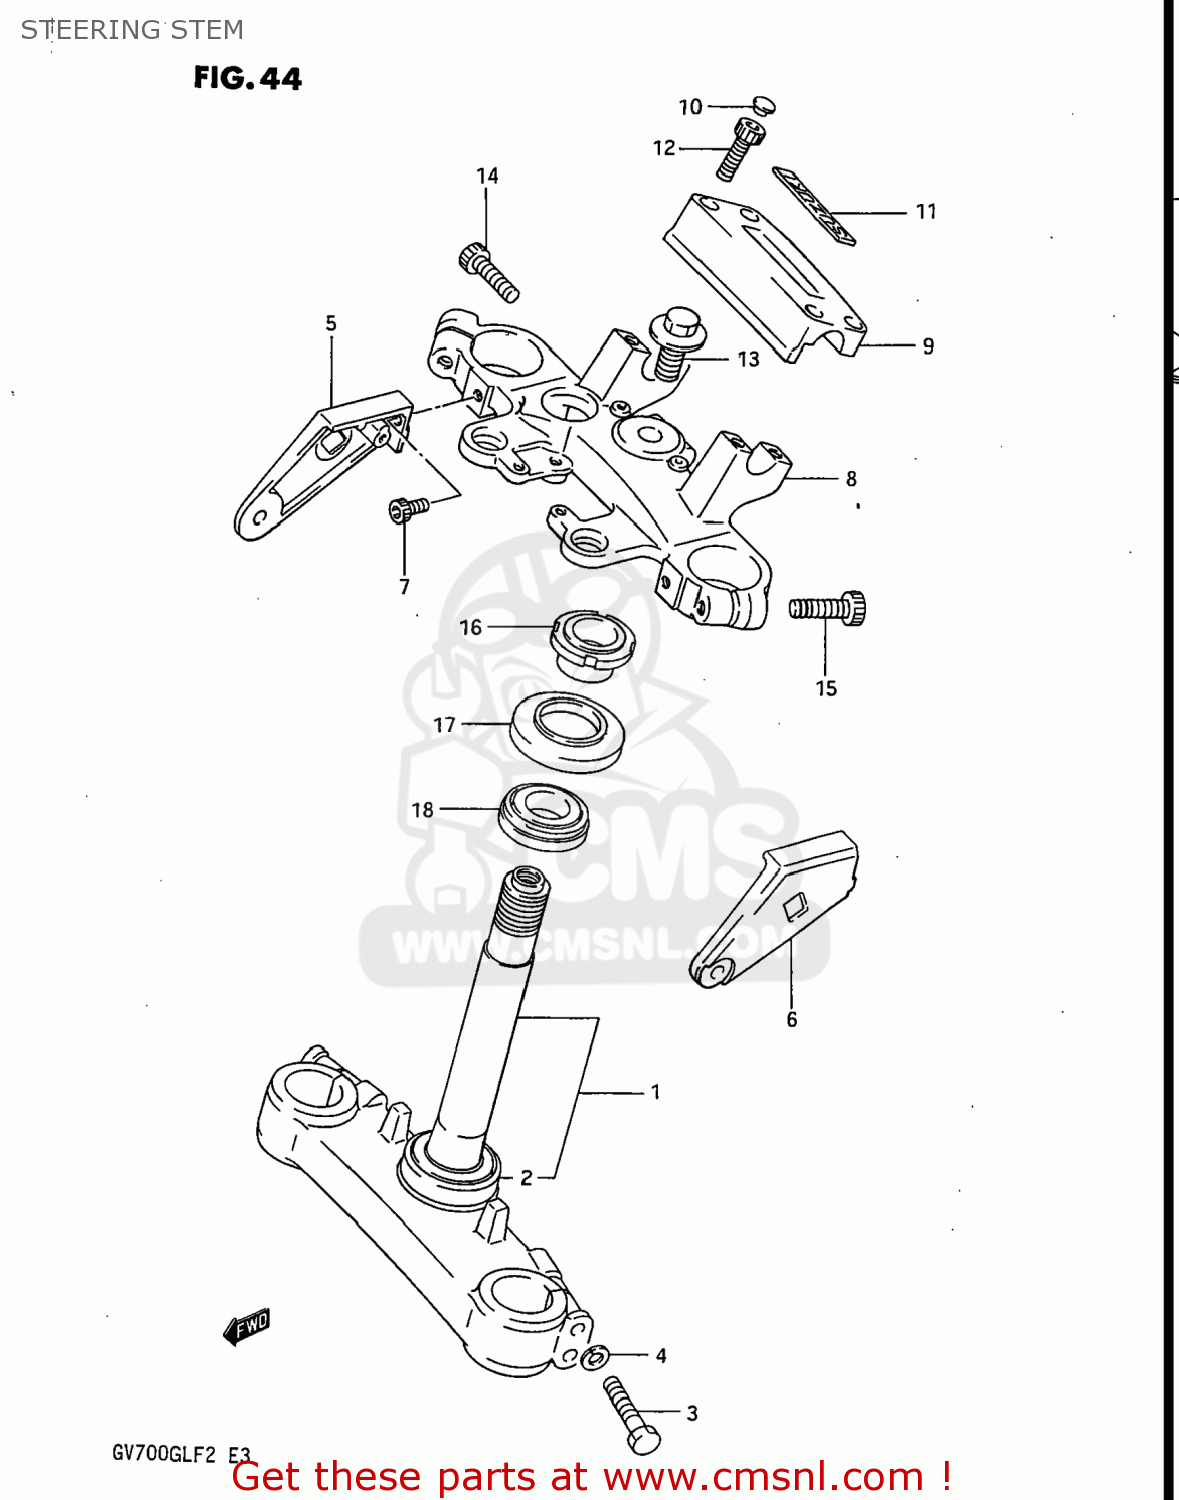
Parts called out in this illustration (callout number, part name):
1	STEM,STEERING
2	BEARING
3	BOLT 8X40
4	LOCK WASHER
5	BRACKET COMP,HEADLAMP
6	BRACKET,HEADLAMP,LEFT
7	BOLT
8	HEAD,STEERING STEM
9	HOLDER,HANDLEBAR
10	CAP(OD:14.5)
11	EMBLEM
12	BOUT
13	BOLT
14	BOLT 8X35
15	BOLT,STEERING STEM HEAD
16	NUT,STEERING STEM
17	DUST SEAL,STEERING UPR
18	TAPER,ROLLER BEARING
